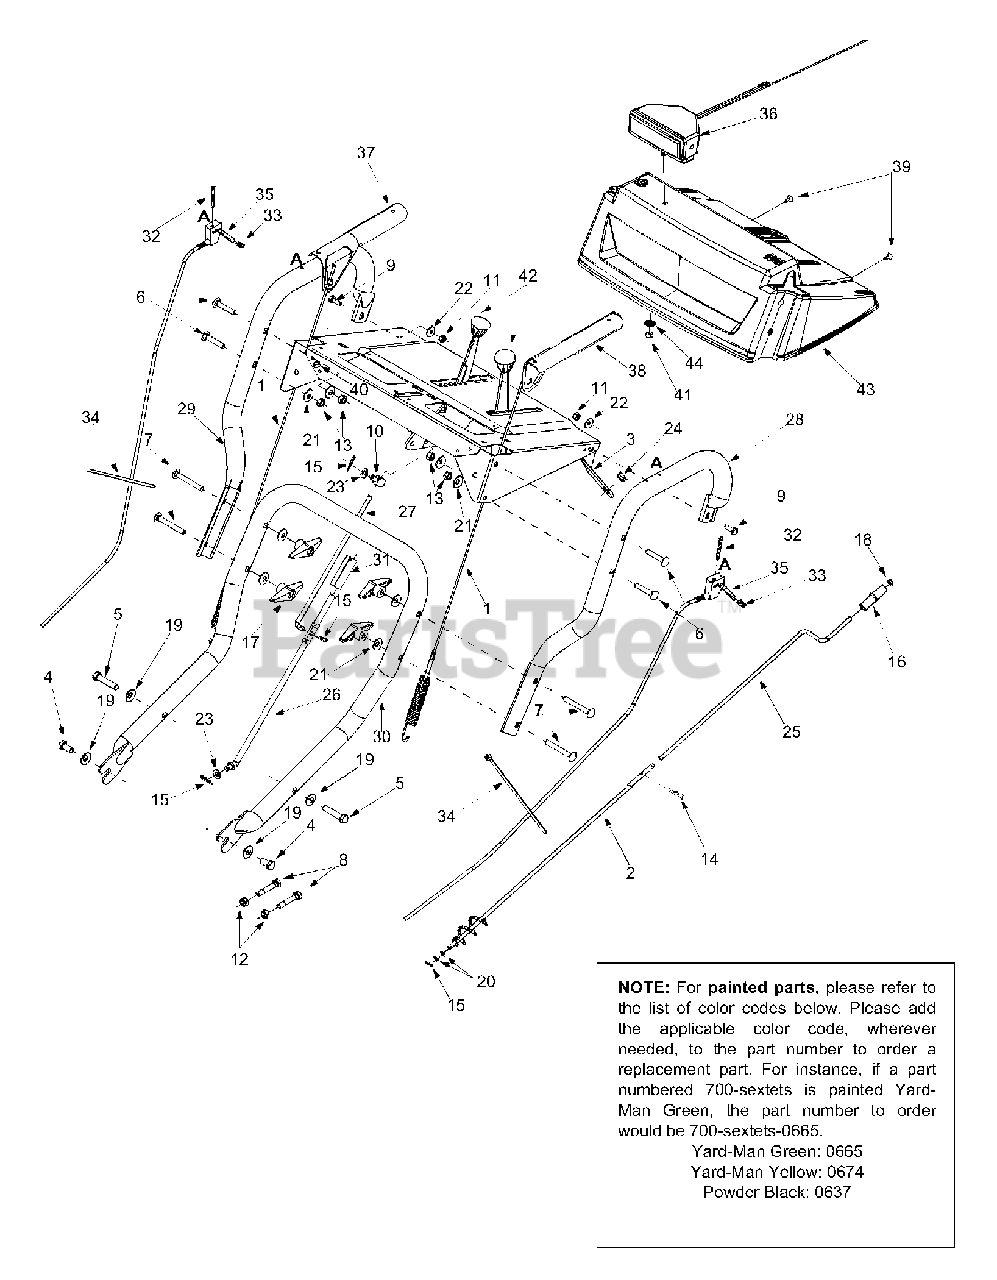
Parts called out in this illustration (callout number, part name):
1	Cable Assembly: Auger/Drive
4	Hex Screw 3/8-16 x .75"
5	Hex Screw3/8-16 x 1.75"
6	Carriage Bolt 5/16-18 x 1.75"
7	Carriage Bolt 5/16-18 x 2.5"
8	Shear Bolt 5/16-18 x 1.75"
9	Hex Screw 1/4-20 x .75"
10	Ferrule
11	Hex Nut 1/4-20
12	Hex Lock Nut
13	Hex Nut
14	Hairpin Clip
15	Hairpin Clip
16	Chute Crank Knob
18	Push Cap
19	Bell Washer
20	Flat Washer
21	Beleville Washer
22	Bell Washer
23	Flat Washer
24	Plastic Bushing
26	Lower Shift Rod
27	Upper Shift Rod
31	Clutch Rod Connector
32	Oval C-Sunk Screw
33	Flat Weld Nut
34	Cable Tie
35	Trigger Control
36	Light Assembly
37	Handle Engagement RH
38	Handle Engagement LH
39	Special B Screw
40	Hex Sems Nut
41	Hex Lock Nut
42	Shift Knob
43	Handle Panel
44	5/16 Washer
